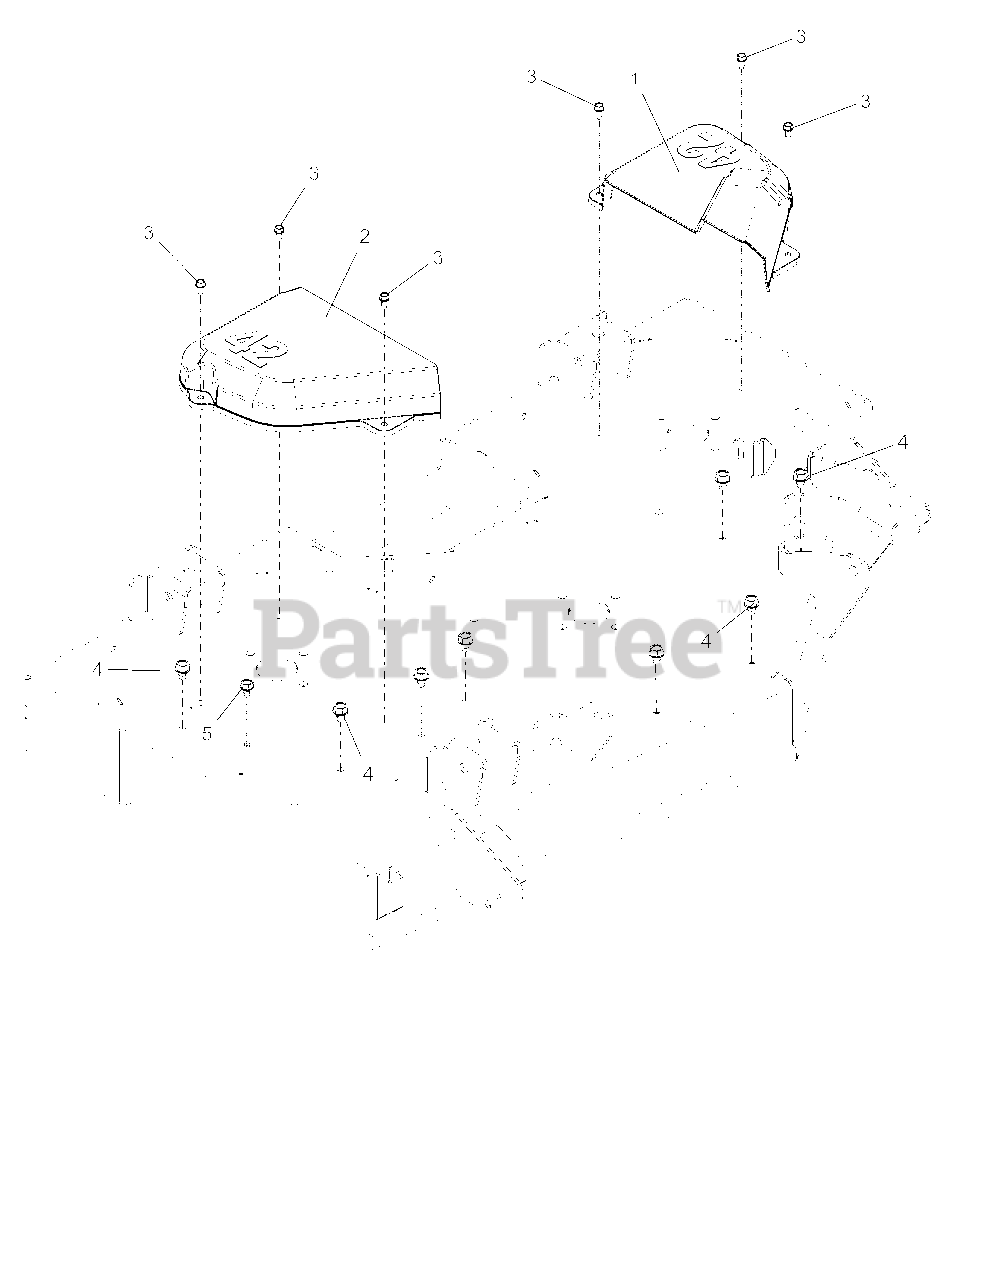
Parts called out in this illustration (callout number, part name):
1	COVER, BELT 42" LH
2	COVER, BELT 42" RH
3	SCR-TAP .25-20X.50 HWH ZCC
4	SCR,TAP .375-16X.50 HWH TR ZCC
5	SCR,TAP .312-18X.50 HWH TR ZCC
